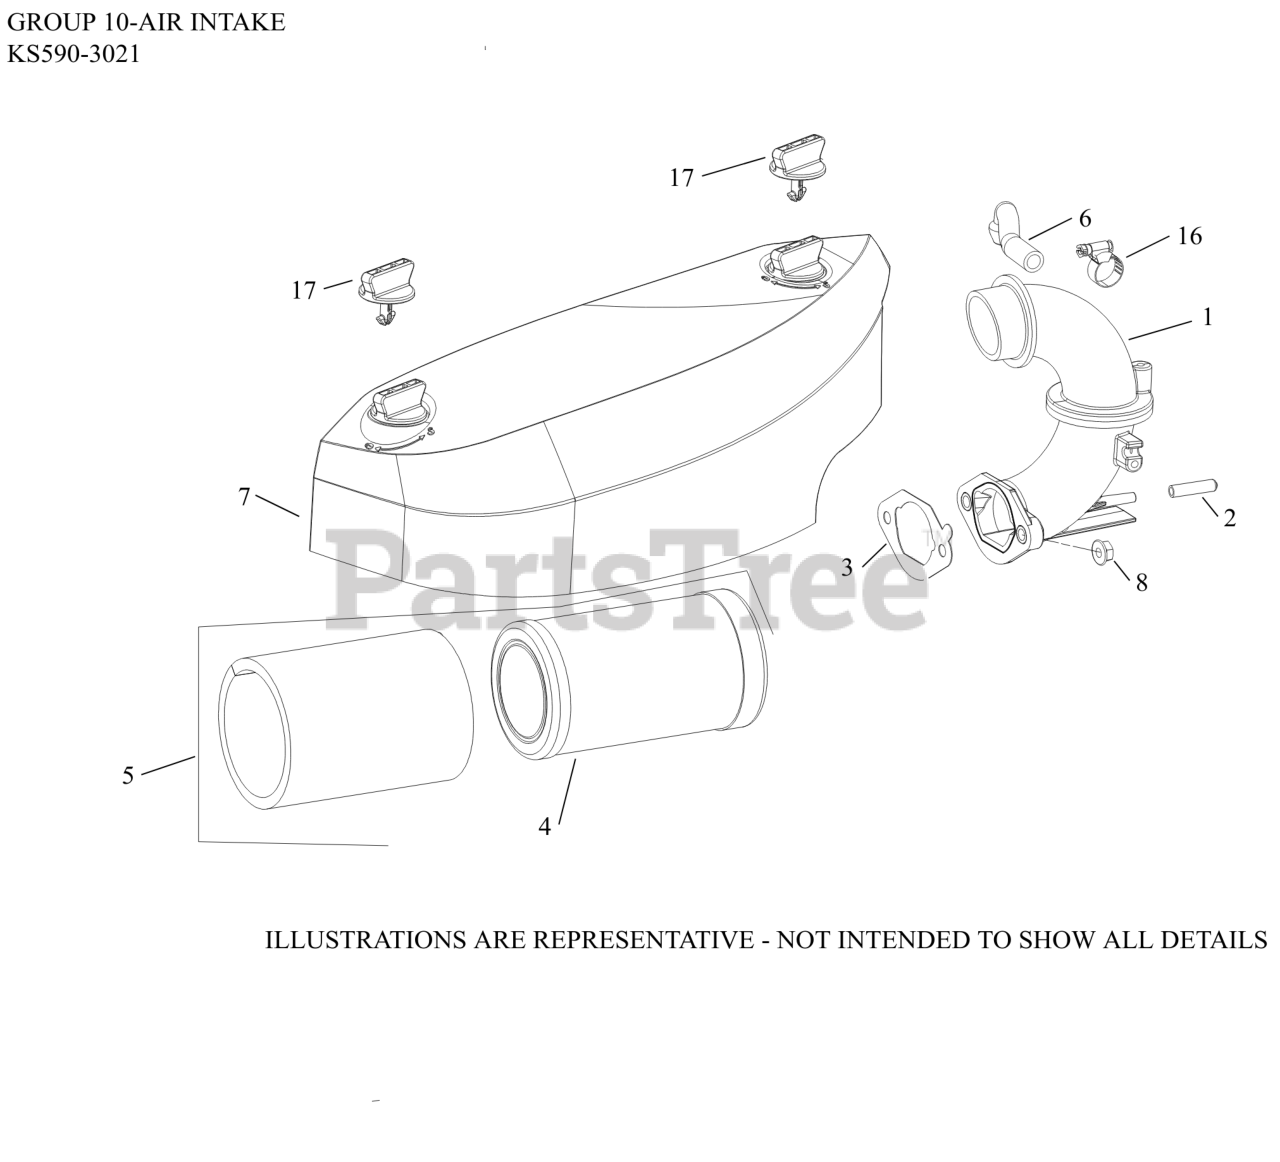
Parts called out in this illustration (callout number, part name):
1	ADAPTER, AIR CLEANER ASSY
2	CAP, MASKING
3	GASKET, CARBURETOR
4	ELEMENT, AIR FILTER
5	AIR FILTER KIT (STD)
6	HOSE, BREATHER
7	COVER, AIR CLEANER ASSY
8	NUT, FLG M6X1.0
16	CLAMP, HOSE (KM)-USE 25 237 31-S
17	KNOB, AIR CLEANER COVER
